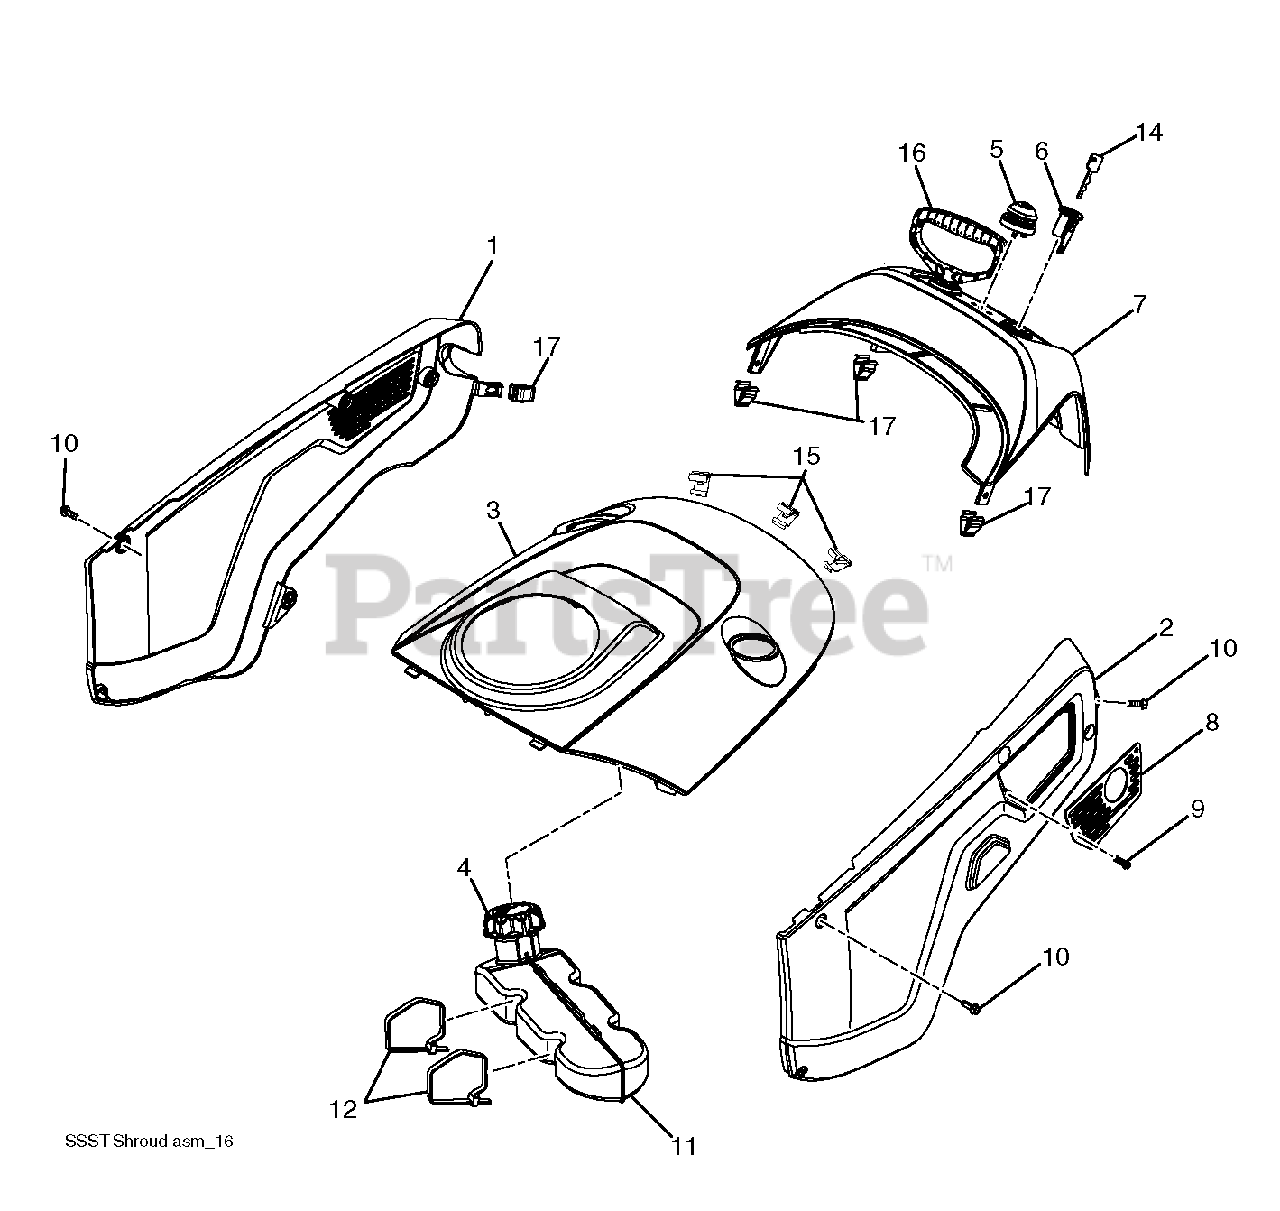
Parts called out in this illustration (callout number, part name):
4	CAP ASM.FUEL.2.25"FR.
5	RP BULB.PRIMER
6	KEY HOUSING
7	TOP.REAR.COVER
8	PLATE.EXHAUST.PNT.
9	SCREW.HX.13X.750
10	SCREW.PAN.HD.TORX.1/4-20X.750
11	TANK.FUEL.ASM
12	TIE.CABLE.24.5X.29.NYLON.WHITE
14	KEY
16	RP HANDLE.STARTER
